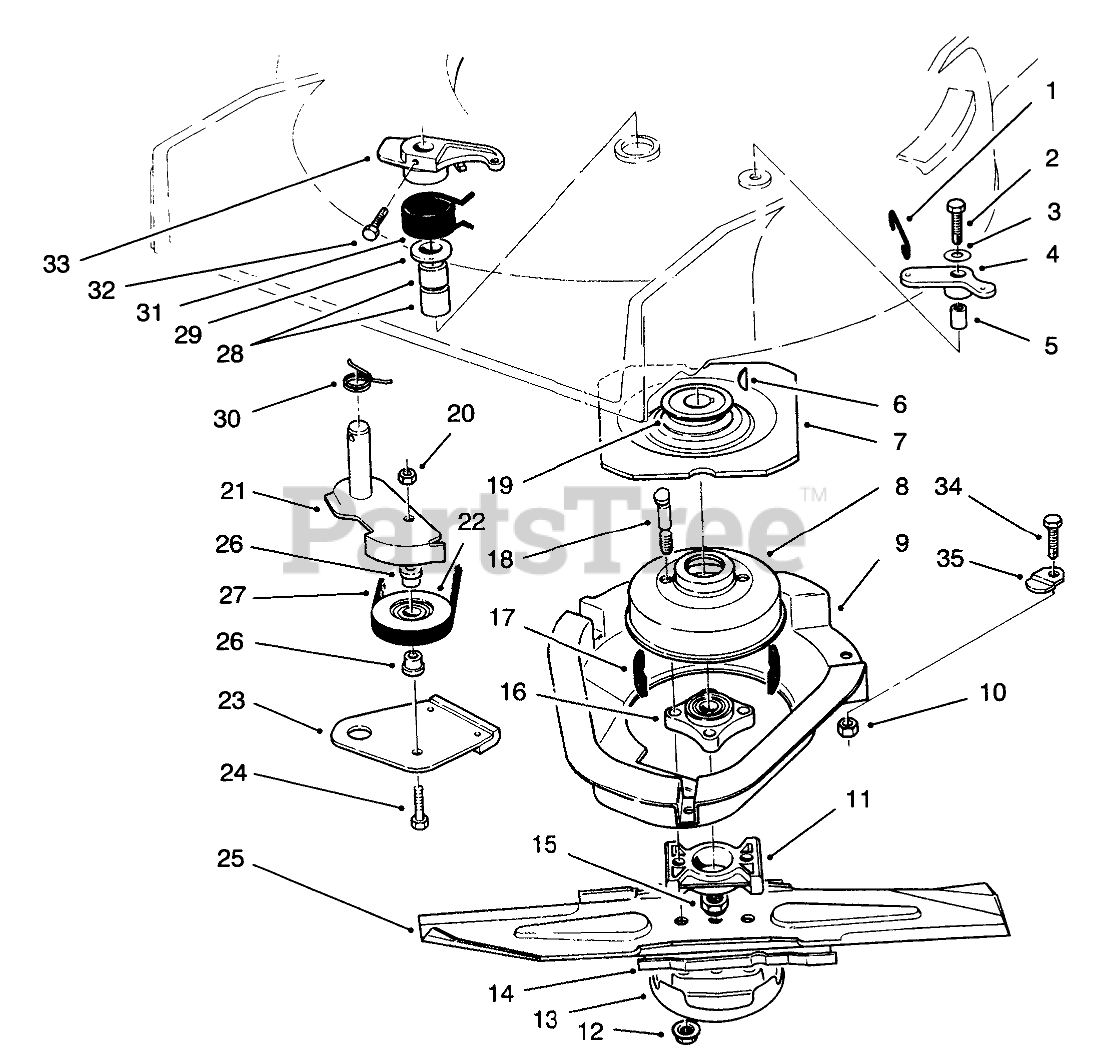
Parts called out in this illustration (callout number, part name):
1	LINK-CONTROL
2	SCREW-HH
3	WASHER-PLAIN
4	BELLCRANK
5	SLEEVE-BELLCRANK
6	KEY-WOODRUFF
7	Flywheel
8	Drum-Brake
9	Shield
10	NUT-LOCK, NI
11	SPACER-BLADE
12	NUT-LOCK
13	CUP-SCALP, ANTI
14	Accelerator
15	NUT-LOCK, NI
16	HUB ASM
17	DAMPENER-VIBRATION
18	BOLT-BLADE
19	PULLEY-DRIVER
20	NUT-LOCK, NI
21	ARM-IDLER
22	PULLEY-IDLER
23	BRAKE PLATE ASM
24	SCREW-HH
25	Blade
26	SPACER-PULLEY, IDLER
27	V-BELT
28	BEARING
29	WASHER
30	SPRING-TORSION
31	SPRING-TORSION
32	SCREW-HH
33	LEVER
34	SCREW-HH
35	SHIELD-RETAINER
